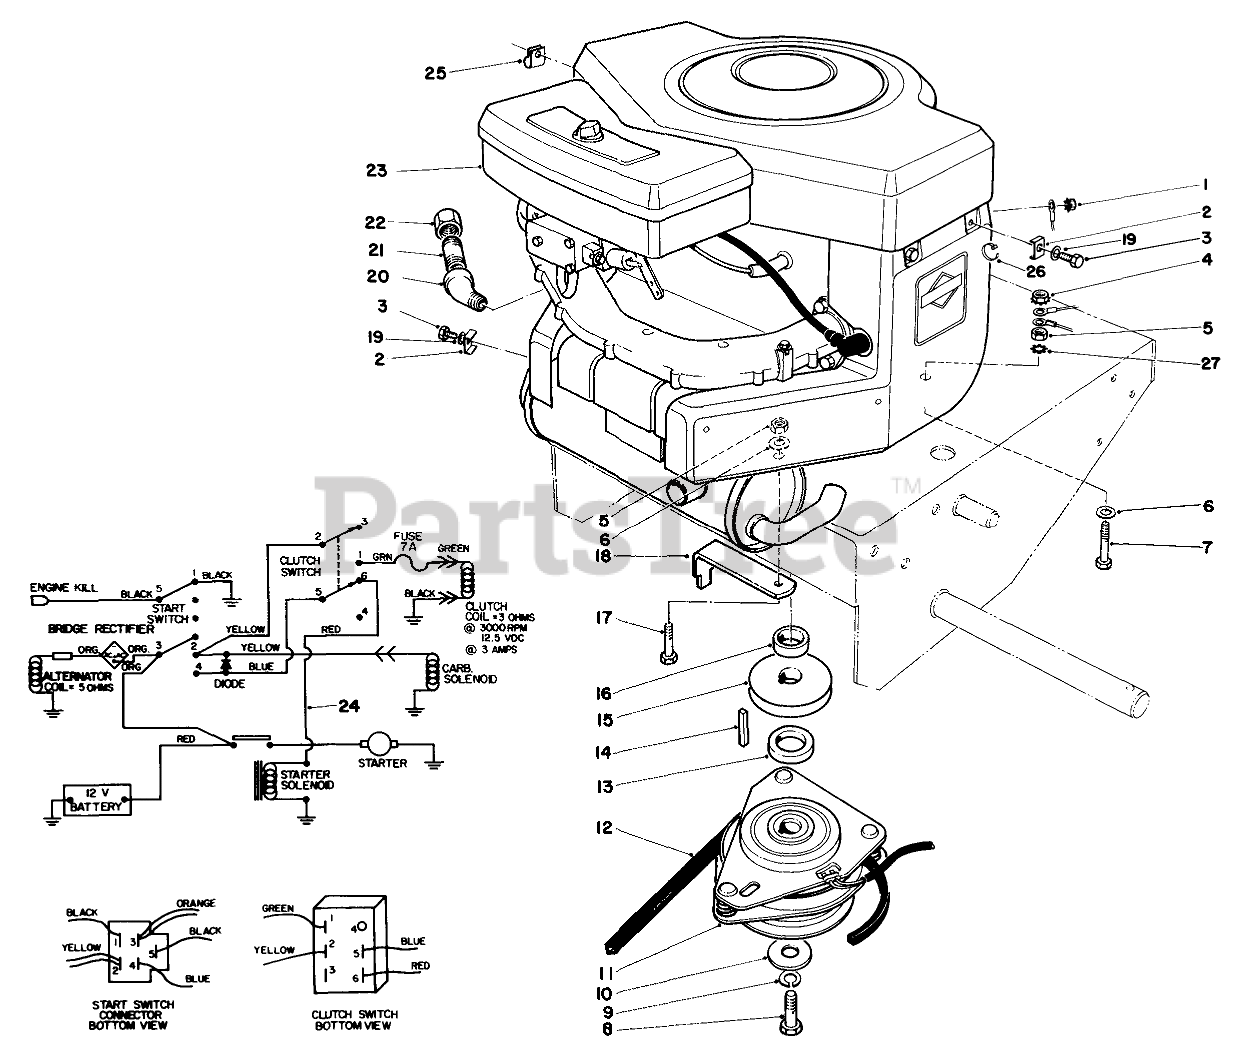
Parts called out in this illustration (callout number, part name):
1	NUT-KEPS
2	CLAMP-CABLE
3	SCREW-HH
4	NUT-KEPS
5	NUT-LOCK, CONE
6	WASHER-PLAIN
7	SCREW-HH
8	SCREW-HH
9	WASHER-LOCK
10	WASHER-CLUTCH
11	CLUTCH/BRAKE
12	V-BELT, DRIVE
13	SPACER-LOWER
14	KEY-SQUARE
15	Pulley-Drive
16	Spacer-Upper
17	SCREW-HH
18	Retainer-Clutch
19	WASHER-LOCK
20	ELBOW
21	NIPPLE
22	CAP-PIPE
23	Engine
24	16 HP WIRE HARNESS
25	CLAMP-R
26	TIE-CABLE
27	WASHER-LOCK
